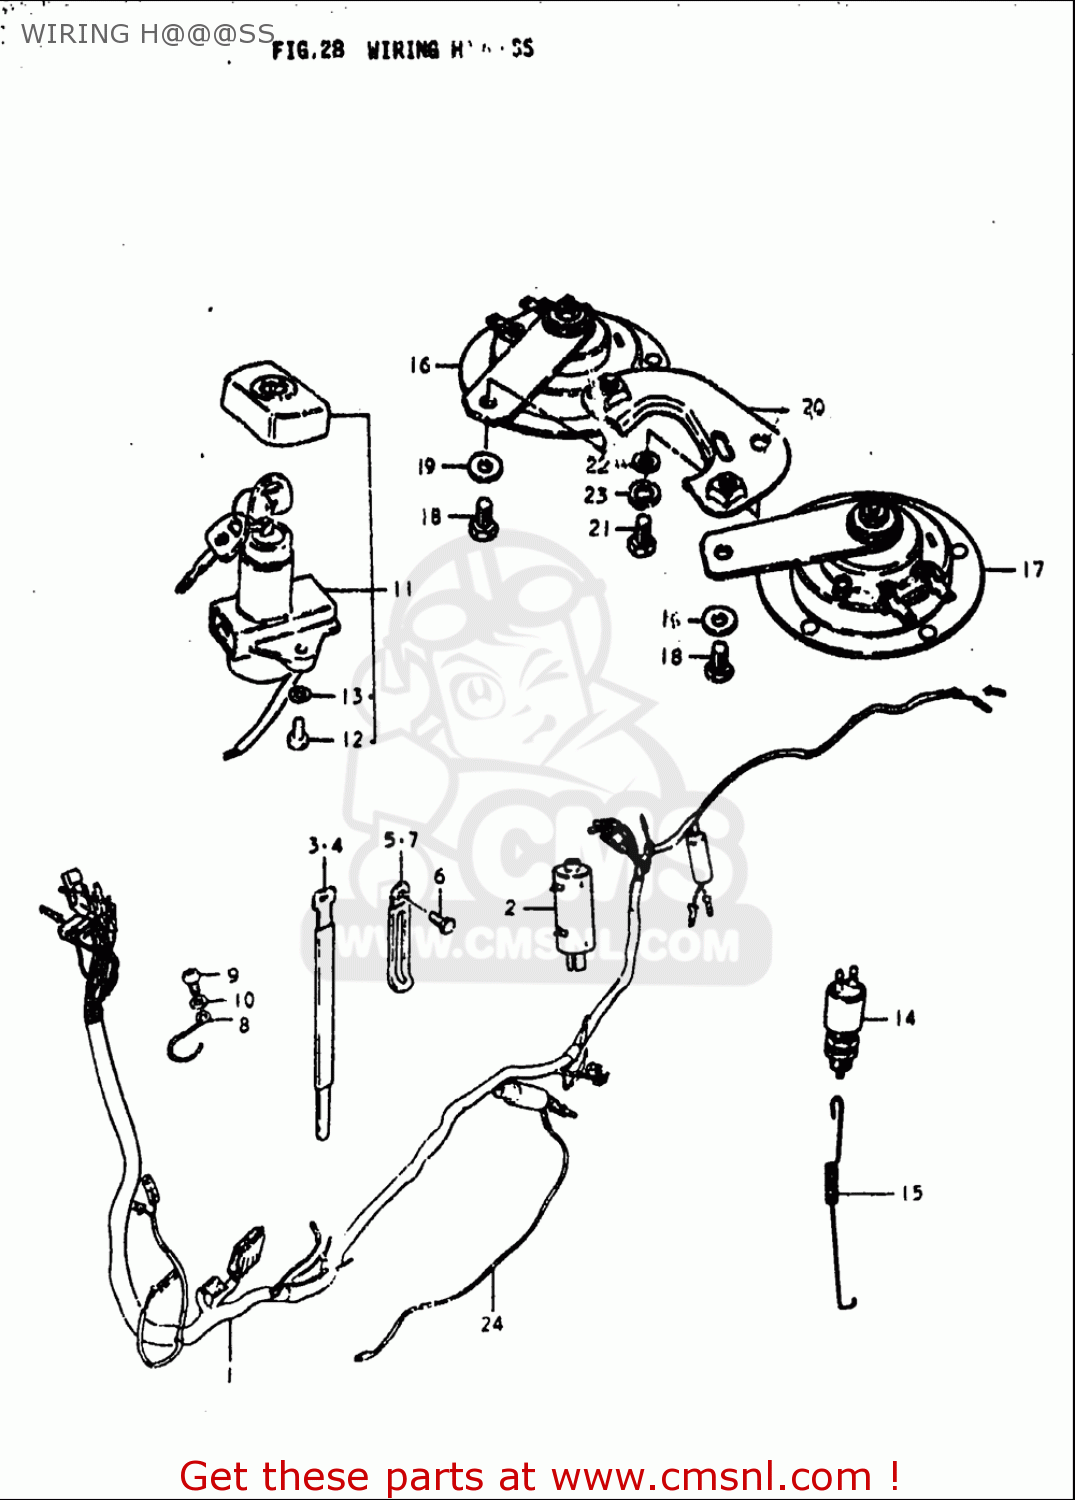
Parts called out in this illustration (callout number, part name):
2	BOOT,WIRING HARNESS
3	CLAMP(L:120)
4	CLAMP
5	CLAMP(L:80 T:1.0)
6	BOLT
7	CLAMP(L:120 T:1.0)
8	CLIP,WIRING HARNESS
9	SCREW
10	WASHER
11	SWITCH ASSY,IGNITION
12	BOLT
13	WASHER,LOCK
14	SWITCH ASSY,BRAKE LAMP
15	SPRING
16	HORN ASSY
17	HORN ASSY,HIGH PITCHED
18	BOLT
19	WASHER
21	BOLT(8X14)
22	WASHER
23	WASHER,LOCK
24	WIRE,OIL PRESSURE SWITCH LEAD
